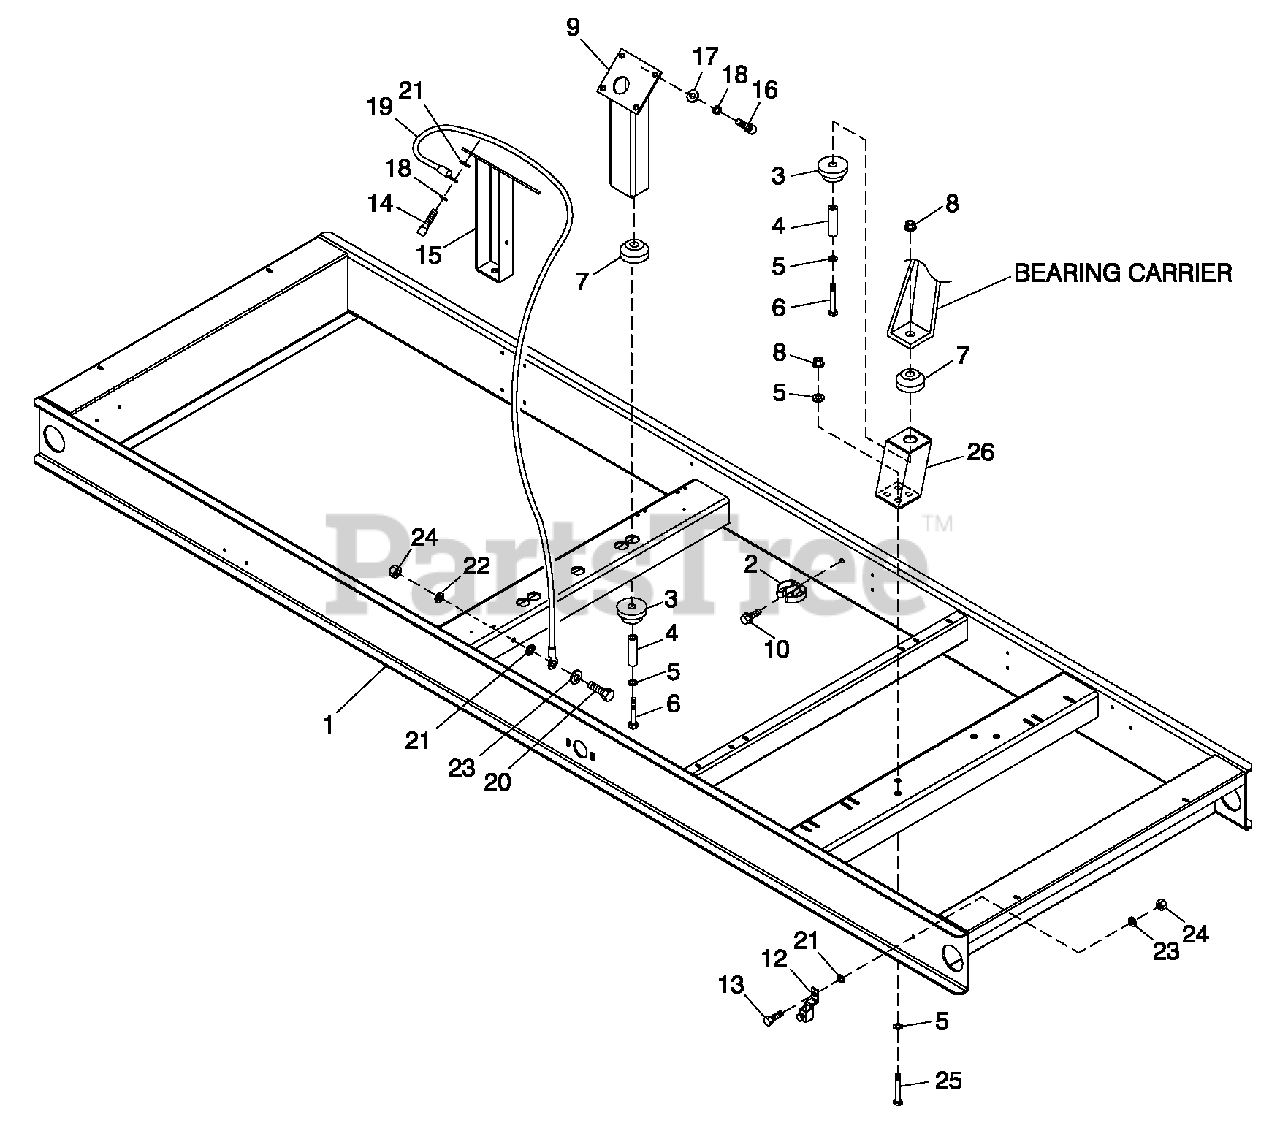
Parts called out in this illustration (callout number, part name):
1	BASECP80KWGB-150KW2P
2	SPRING CLIP HOLDER ,37-.62
3	DAMPENER VIBRATION
4	SPACER .49 X .6 2 X 1.87 PWDR/ZINC
5	WASHER FLAT M12
6	SCREW HHC M12-1.75X 85 G8.8
7	DAMPENER VIBRATION 50 WHITE
8	NUT LOCKING M12-1.75
9	S UPPORT ENG 5.4L LH/RH 6.8L RH
10	SCREW HHTT M4-0.7 X 8 BP
11	WASHER SHAKEPROOFINT1/4
12	LUG SOLDERLESS 3/0-#4 X 13/32 CU
13	SCREW HHC M8-1.25X 25 G8.8
14	SCREW SHC M10-1.5X 60 C12.9
15	SUPPORT ENGINE LH
16	SCREW SHC M10-1.5X 30 G12.9
17	WASHER FLAT 3/8-M10 ZINC
18	WASHER LOCK M10
19	ASSY WIRE 14.00"
20	SCREW HHC M8-1.25X 30 G8.8
21	WASHER SHAKEPROOF INT 3/8
22	WASHER LOCK M8-5/16
23	WASHER FLAT 5/16-M8 ZINC
24	NUT HEX M8-1.25 G8 YEL CHR
25	SCREW HHC M12-1.75X 40 G8.8
26	TOWER GB COMPROD C5
